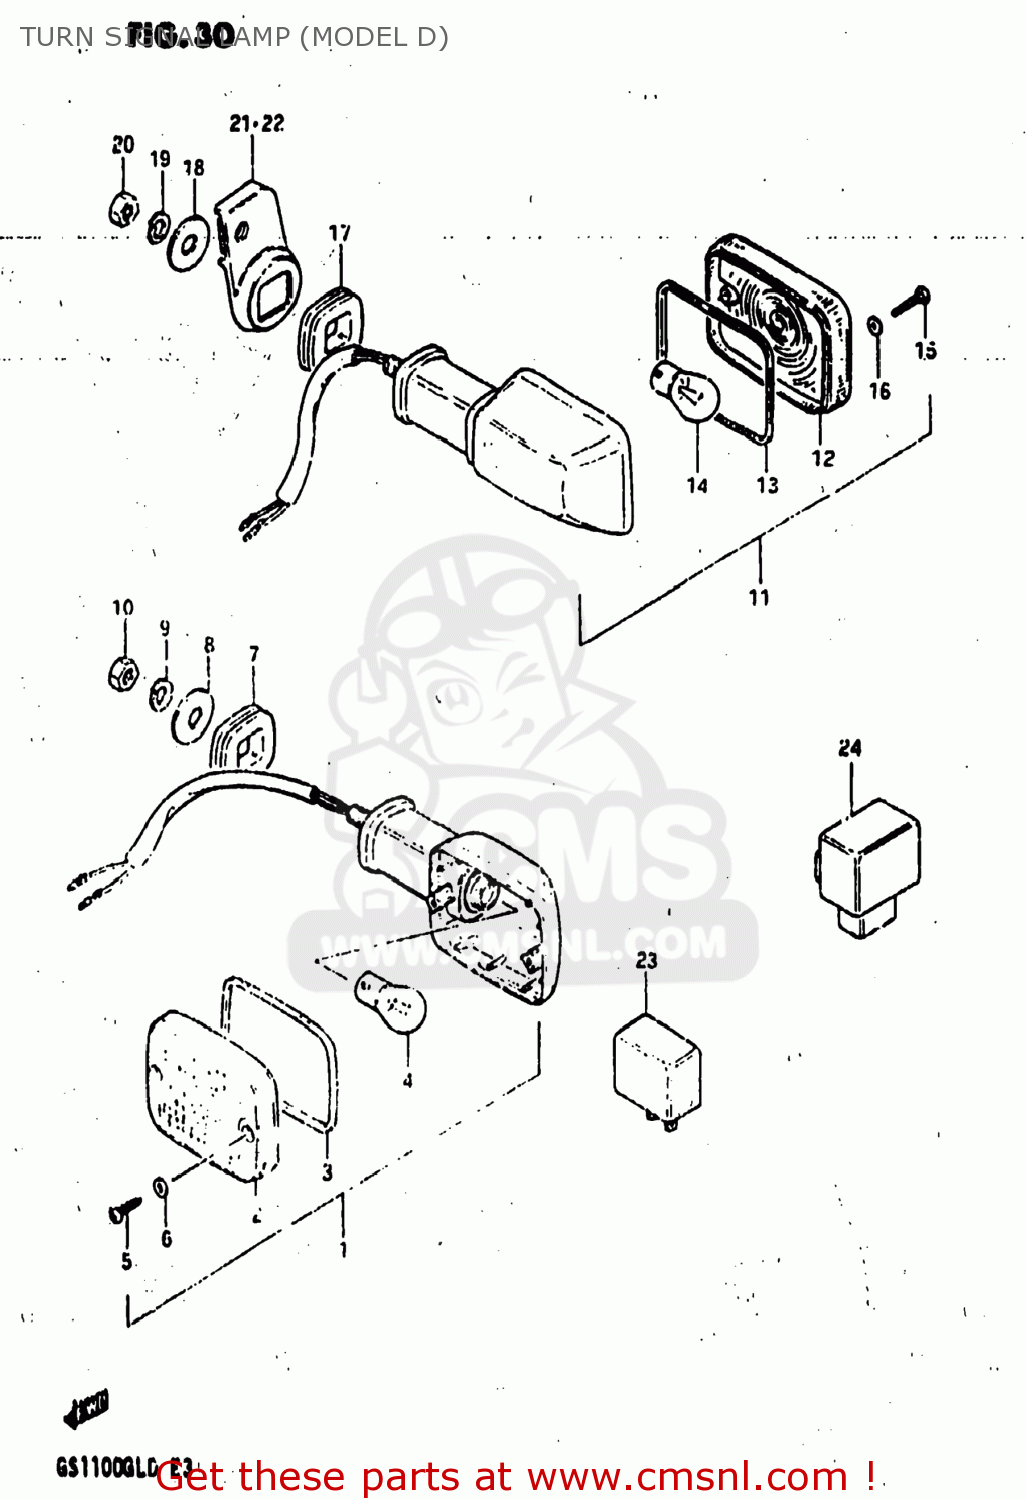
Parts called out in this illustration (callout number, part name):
1	LAMP ASSY,FR TURN SIGNAL
2	LENS
3	GASKET (NAS)
4	BULB(12V23W)
5	SCREW
6	GASKET (NAS)
7	CUSHION
8	WASHER (10.5X30X2.3)
9	LOCK WASHER
10	NUT
11	LAMP ASSEMBLY,REAR TURN SIGNAL
12	LENS
13	GASKET (NAS)
14	BULB(12V23W,STANLEY,A4577A)
15	SCREW
16	GASKET (NAS)
17	CUSHION
18	WASHER (10.5X30X2.3)
19	LOCK WASHER
20	NUT
21	BRACKET,REAR TURN SIGNAL
22	BRACKET,REAR TURN SIGNAL
23	RELAY ASSY,TURNSIGNAL
24	UNIT,TURN SIGNAL CONTROL
